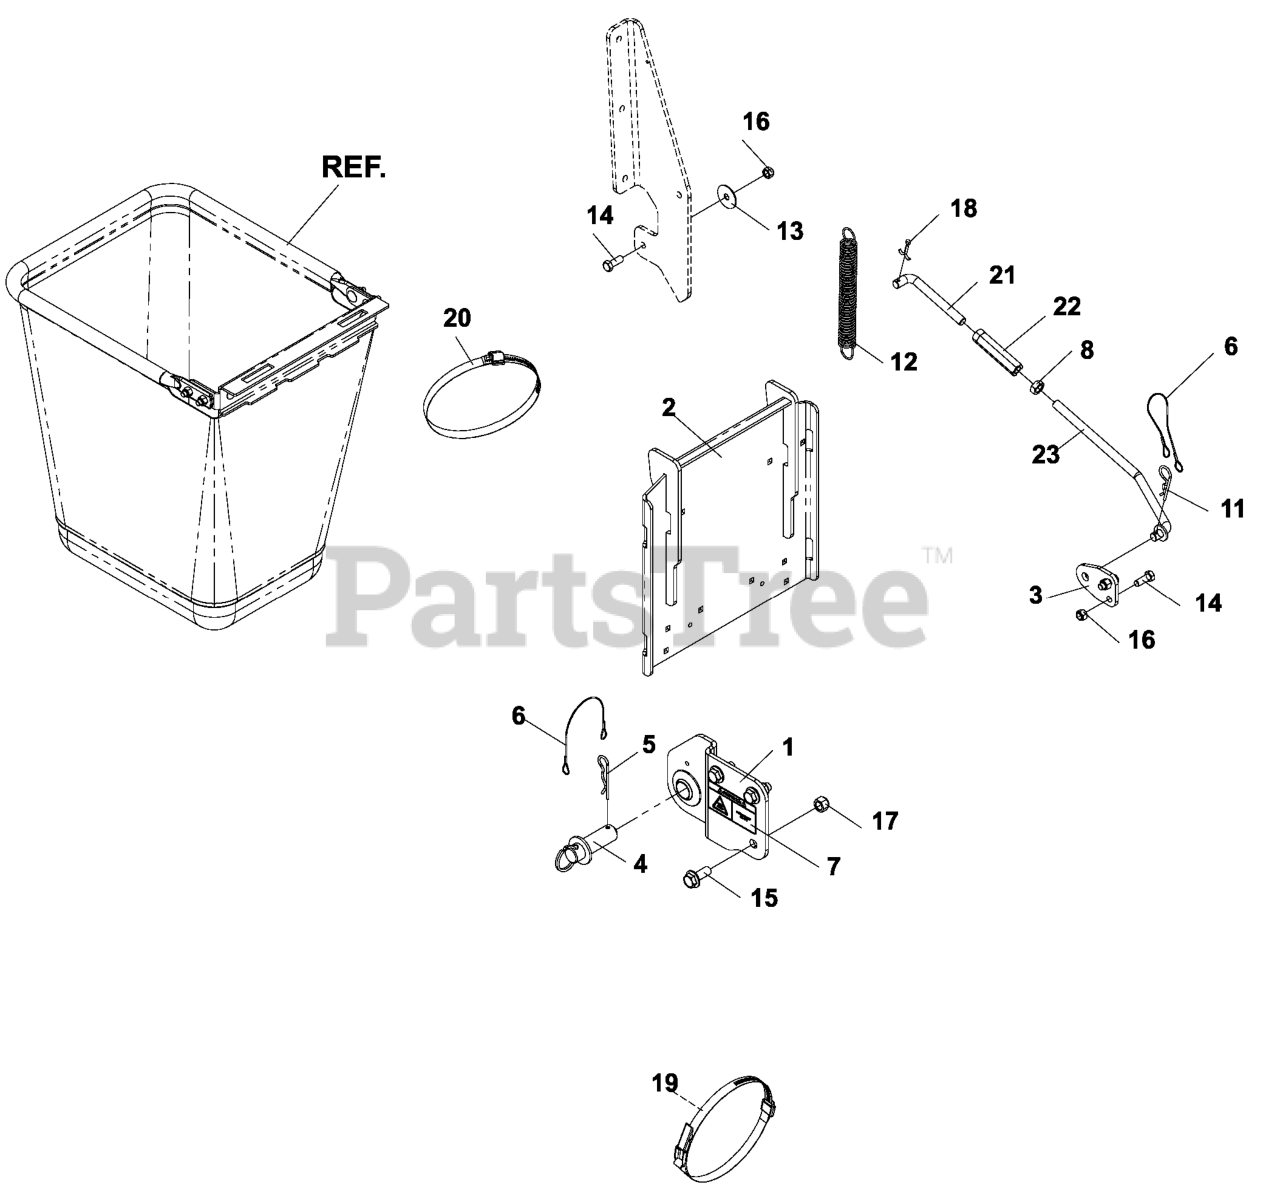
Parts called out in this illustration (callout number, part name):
1	HITCH BRACKET W/ DECAL MID
2	REAR GUARD WELDMENT
3	SUPPORT BRACKET
7	DECAL, HOT SURFACE
8	NUT 1/2-20 HEX JAM ZD
11	HAIRPIN #4
13	WASHER, FRICTION
14	HCS 3/8-16X1.GRD.5.ZD
15	HCS 1/2C X 1 1/4 SERRATED HEAD
16	NUT 3/8-16 NYLOC
17	NUT 1/2-13 HEX NYLOC ZD
18	COTTER PIN
19	OVER CTR BAND
20	HOSE CLAMP 4-1/8 TO 7"
21	SUPPORT LINKAGE, LH
22	TURNBUCKLE, 1/2
23	SUPPORT LINKAGE, MID
